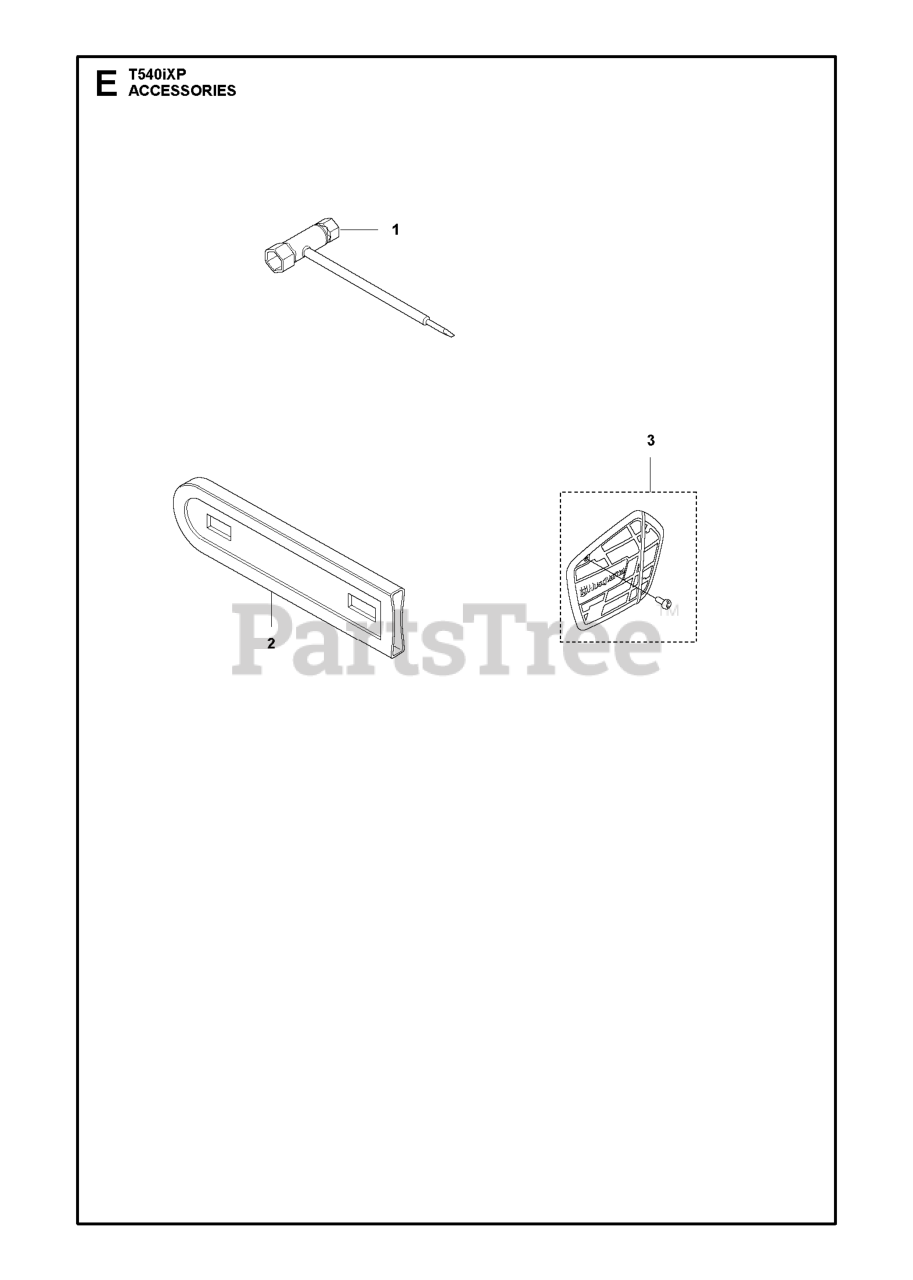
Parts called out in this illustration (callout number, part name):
1	COMBI TOOL
2	BAR PROT/13-16""
3	Covers
